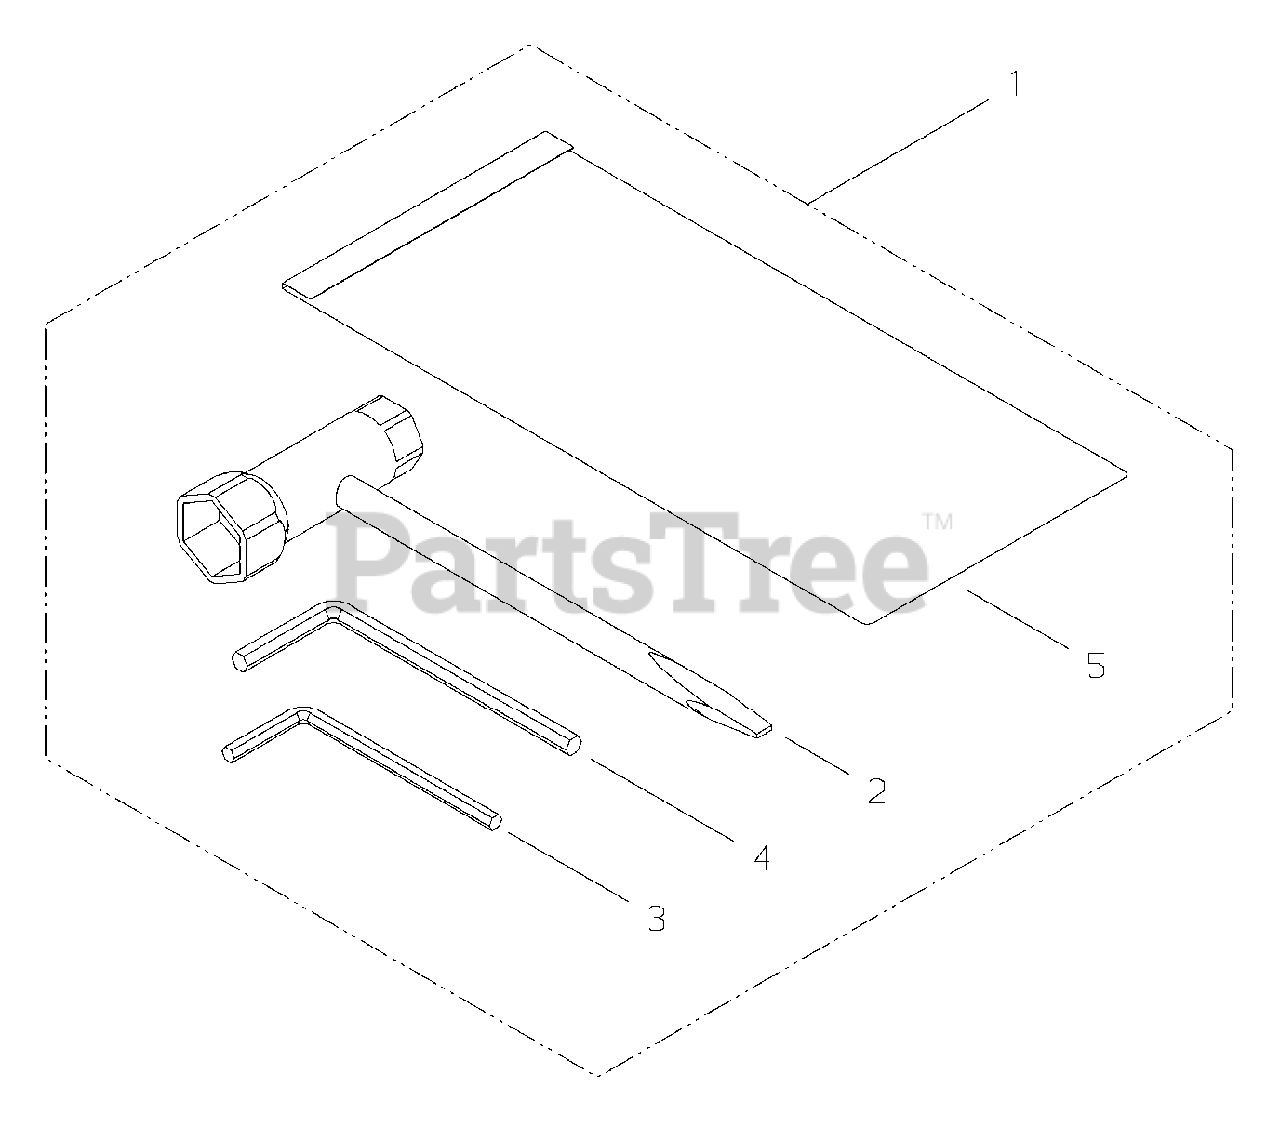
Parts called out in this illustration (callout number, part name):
1	TOOL KIT
2	T-WRENCH - 13X16mm
3	HEX KEY - 4mm
4	HEX KEY - 6mm
5	BAG, TOOL
